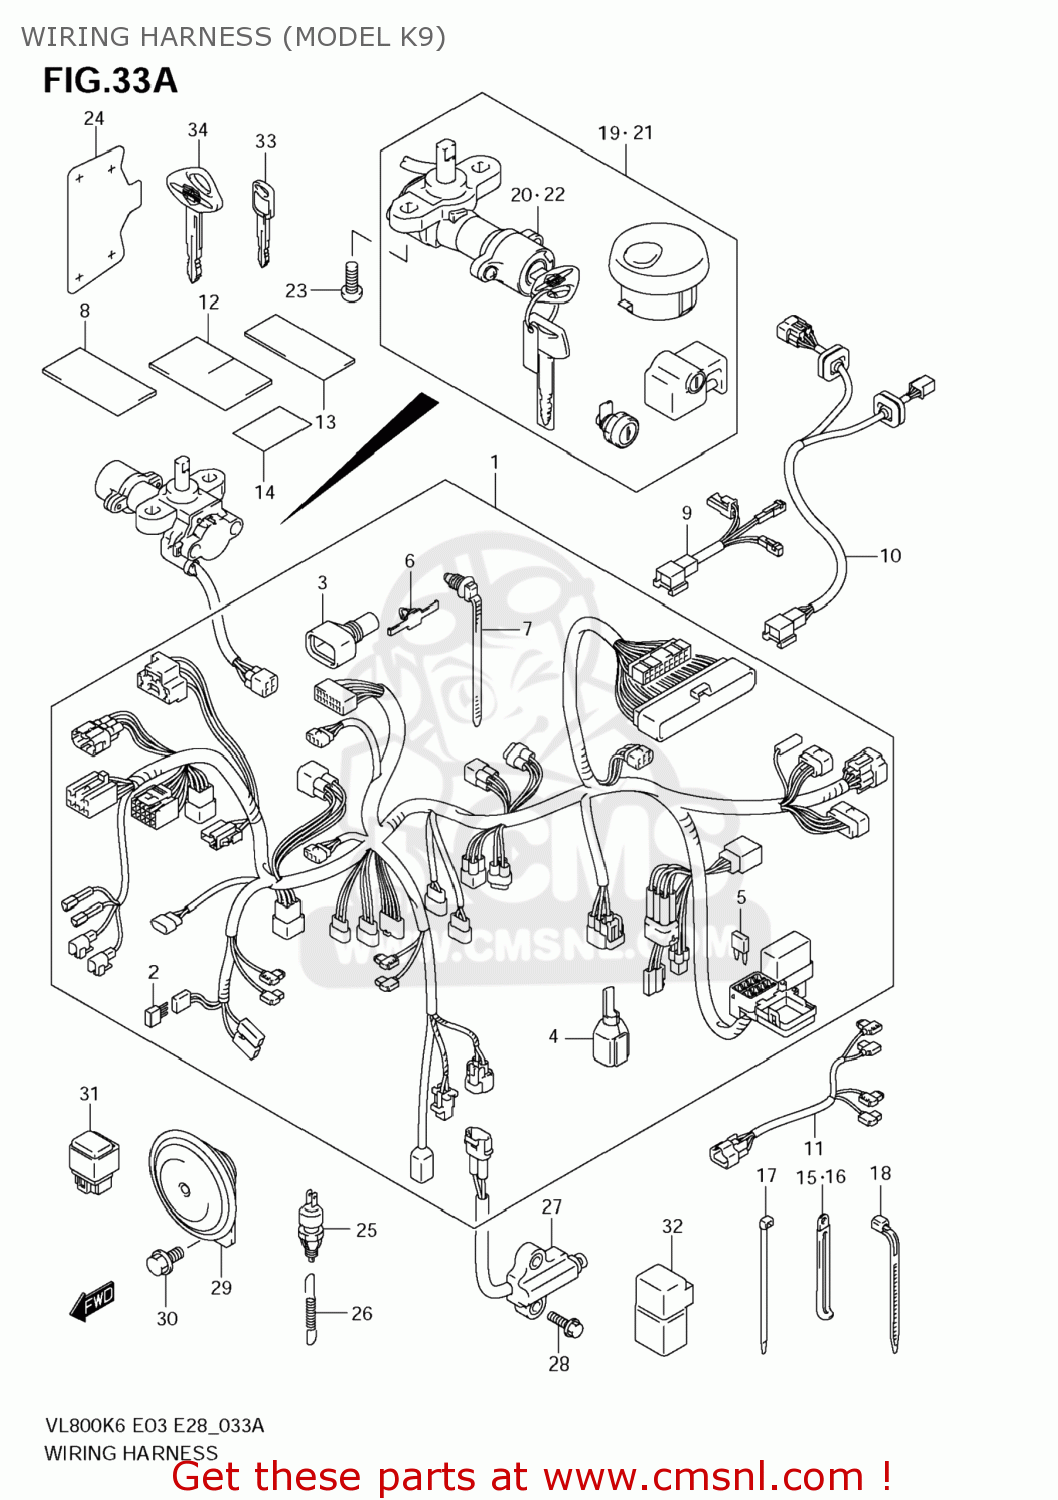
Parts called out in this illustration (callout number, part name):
1	HARNESS,WIRING
2	RECTIFIER ASSY
3	BOOT
4	BOOT
5	FUSE(10A)
6	CLAMP
7	CLAMP(L:154)
8	TAPE,WIRING HARNESS(28X50X0.13
9	WIRE,RR COMB NO.2
10	WIRE,RR COMB
11	WIRE,IGNITION COIL LEAD
12	PROTECTOR,HARNESS(30X50X3)
13	PROTECTOR,WIRING HARNESS
14	PROTECTOR,COWLING UNDER
15	CLAMP(L:80)
16	CLAMP(L:135)
17	CLAMP(L:145)
18	CLAMP(L:165)
19	LOCK SET
20	LOCK ASSY,STEERING
21	LOCK SET
22	LOCK ASSY,STEERING
23	BOLT(8X20)
24	PROTECTOR,IGNITION SWITCH
25	SWITCH ASSY,STOP LAMP
26	SPRING
27	SWITCH ASSY,SIDE STAND
28	BOLT(6X20)
29	HORN ASSY
30	BOLT
31	RELAY ASSY
32	RELAY ASSY
33	KEY,BLANK
34	KEY,BLANK(BOULEVARD)
